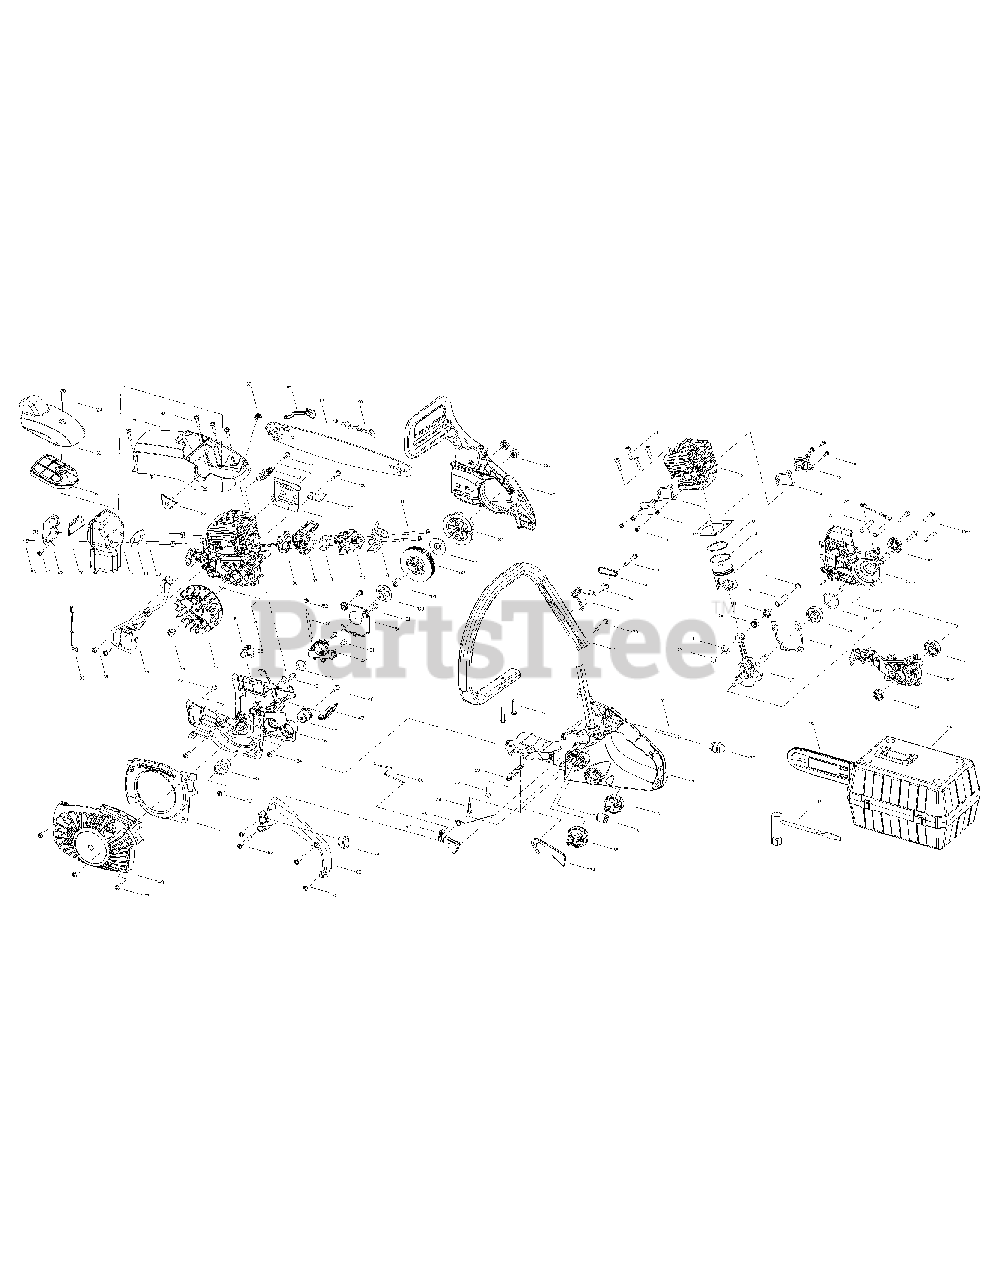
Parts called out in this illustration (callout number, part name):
8	PISTON RING
13	PIN, PISTON
15	CLY CASE ASS' Y
15-1	CLY CASE, LEFT
15-3	CLY CASE, RIGHT
17	CRANK/ROD ASS' Y
25	COVER, MESH
26	SPARK ARRESTER
27	MUFFLER ASS' Y
32	IGNITION ASS' Y
33	NUT
34	FLYWHEEL ASS' Y
35	WOODRUFF KEY
37	ISOLATER ASS'Y, CARBURETER
39	CARBURETER
40	AIR GUIDE
42	SCREW
43	STARTER HOUSING ASS'Y
44	CAP, AIRWAY
45	PLUG, LEFI
47	FIXED, PUSH ROD
48	PLUG, RINGHT
49	PUMP ASS'Y
50	CAP, ANTI-DUST
52	CONNECTOR
53	SPARK PLUG
55	CATCH:CHAIN
57	CAP, ADJUST
59	HOLDER, CHOKE LEVER
60	LEVER, CHOKE
61	AIR FILTER ASS.Y
62	TOP COVER
63	HANDLE, LB
67	TRIGGER, THROTTLE
69	FIXED, PLATE
71	HANDLE, FRONT
73	CAP, SPRING
74	TRIGGER, RELEASE
75	OIL CAP ASS' Y
76	HANDLE ASS'Y (R)
82	DRUM ASS'Y
84	CLUTCH ASS'Y
85	BRAKE KIT ASS' Y
87	FUEL FILTER
88	FUEL CAP ASS'Y
94	CARRY CASE
